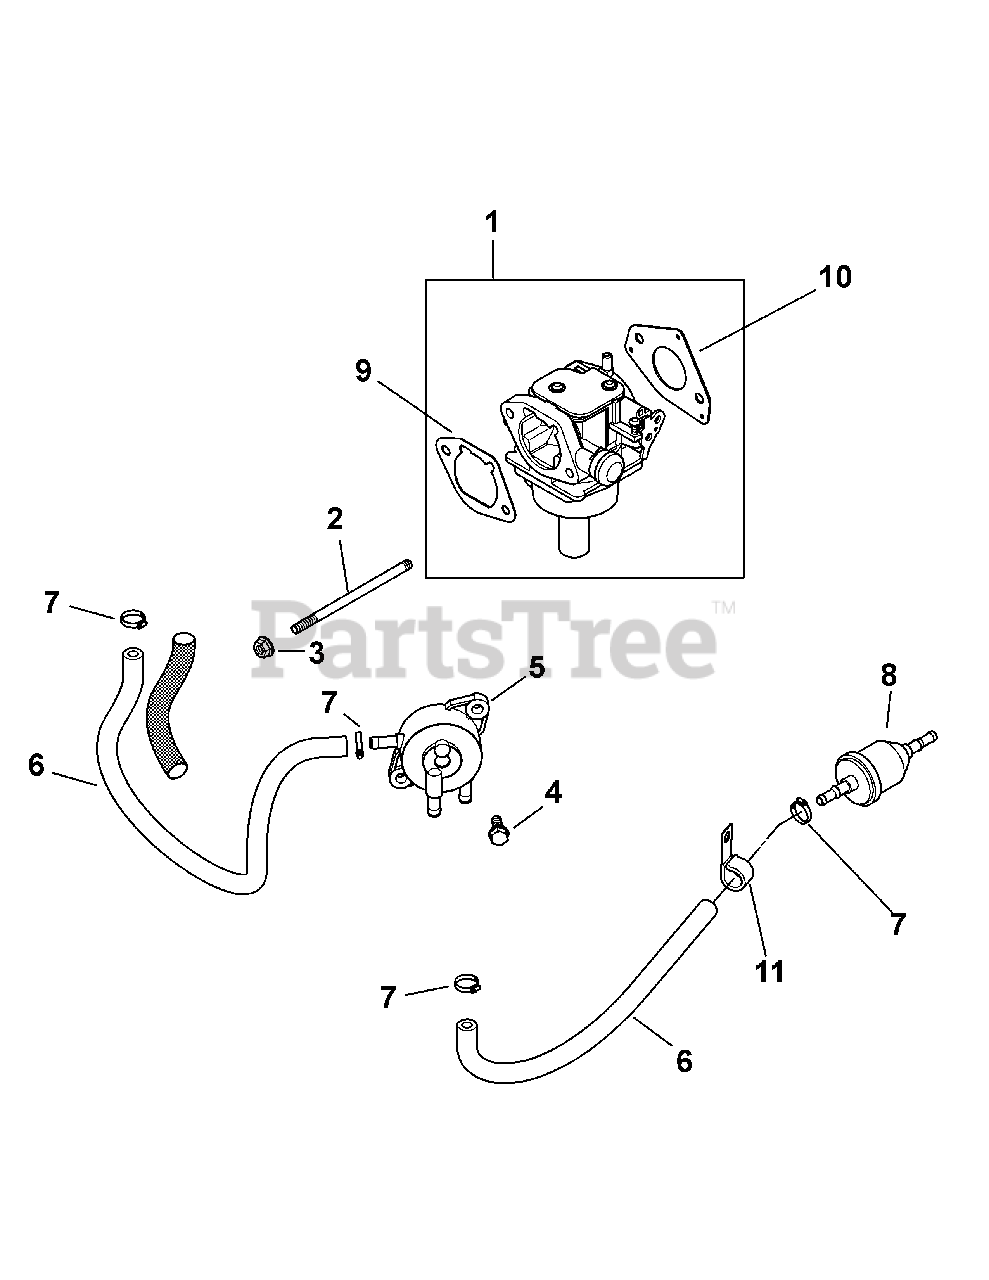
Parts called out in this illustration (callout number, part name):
1	Carburetor Kit
2	Stud, M6 x 1.0 x 106
3	Flange Nut, M6 x 1.0
4	Tap Screw, M6 x 1.7 x 18
6	Fuel Line
7	Hose Clamp, 1/2
9	Air Cleaner Base Gasket
10	Carburetor Gasket
